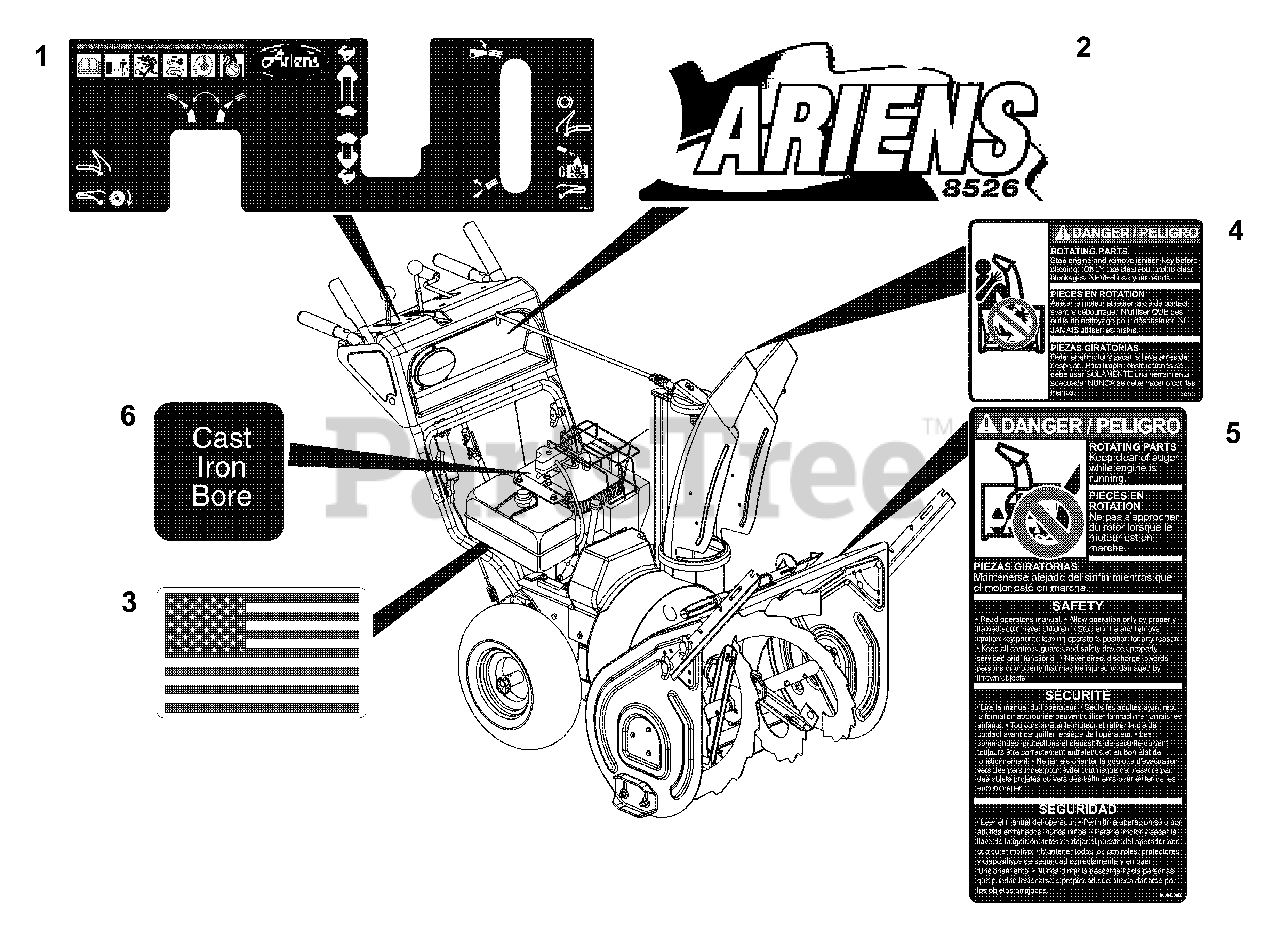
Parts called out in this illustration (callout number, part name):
1	DECAL, CONTROL PANEL, ST8526
2	DECAL, FRONT PANEL, ST8526
3	DECAL, AMERICAN FLAG
4	DECAL, DANGER - ROT. PARTS
5	DECAL, DANGER
6	DECAL - CAST IRON BORE
